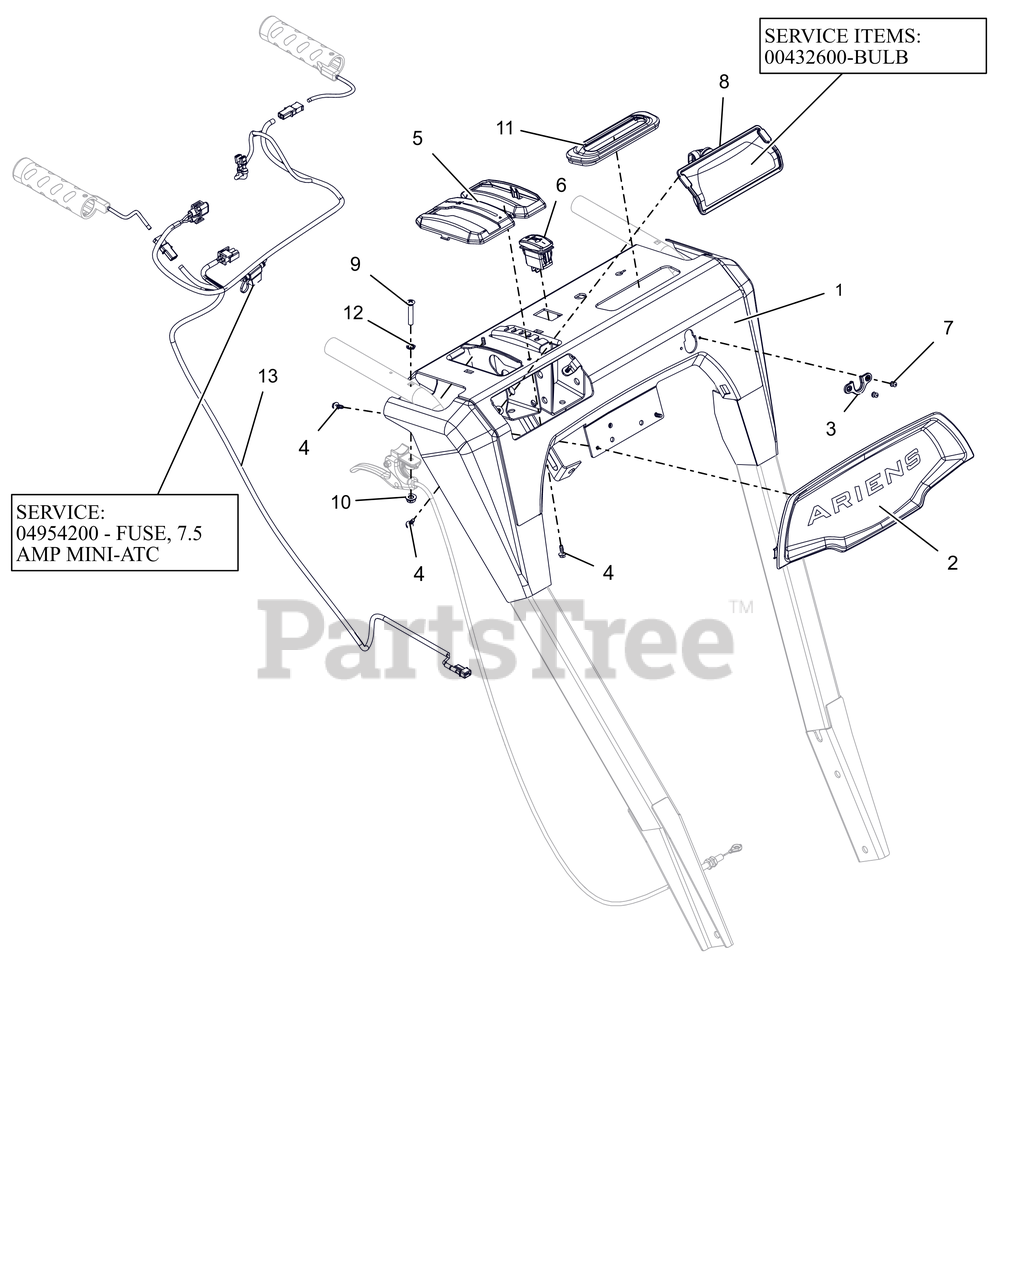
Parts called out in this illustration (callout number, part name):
1	PANEL, DASH-HYDRO EFI W/DECAL
2	BEZEL, DASH - ARIENS LG DASH
3	GROMMET, CABLE, QUICK TURN 2
4	SCR-TAP #10X.50 BOSS INDHXHD
5	BEZEL, SHIFT - HYDRO SNOW
6	SWITCH,ROCKER SPST-ON/OFF
7	RVT-POP #43 .125X.313 STL ZINC
8	HEADLIGHT ASY, HALO 20W 2SHOT
8	BULB, LIGHT-HALOGEN 20W
9	SCR-MCH .25-20X1.50 OVAL HD
10	@NUT-LK-CTR-FLG .25-20 YWZC
11	GROMMET, BOOT, QUICK TURN
12	WSHR-LK-INT .250 TH TYA
13	HARNESS,LIGHT&WARMER - EFI
13	FUSE, 7.5 AMP MINI-ATC
